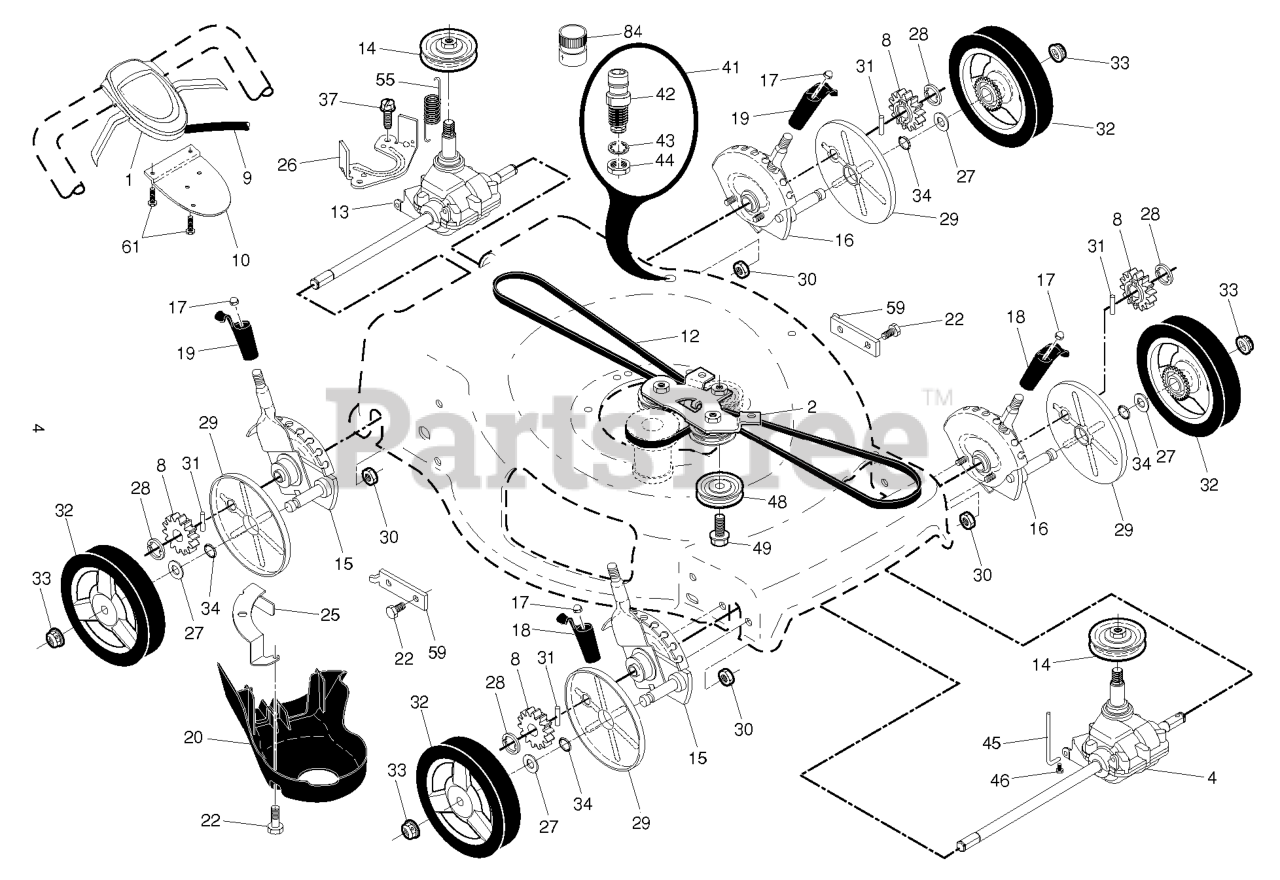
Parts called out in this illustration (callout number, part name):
1	CONTROL.22+AWD.AW2.BS.GRY/BLK
2	BRACKET.ASM.AWD.BZP
4	RP TRANSMISSION.22+.AWD.FRONT
8	PINIION.14.TOOTH.RGD
9	CABLE.DRIVE.RWD.WALK.
10	BRACKET.DRIVE.CONTR.GEN2.BLACK
12	BELT.DRIVE.AWD.PLUS.13
13	TRANSMISSION.22+AWD.WALK.MOWER
15	KIT.ADJ.22+QP.RT F/R.BLK.
16	KIT.ADJ.AWD.22+LT.F/R.BLK
17	NUT.PUSH.156
18	KNOB.ADJUSTER.LW.BLK
19	KNOB.ADJUSTER.REAR.BLACK
20	COVER.REAR.DRIVE.22+2013
22	BOLT.5/16HEX.WHS.HD
25	BRACKET.DRIVE.COVER.RGD.BZP
26	BRACKET.TRAN.BELTKEEPER.22+RGD
27	WASHER FLUT
28	E-RING 7/16 RE
29	COVER.DUST.WHEEL.INNER.WALK
30	NUT.FLANGE.1-4-20-SERR
31	PAWL, DRIVE
32	WHEEL.8".AWD.3SP.EXT.DR.GREY
33	NUT.HEX.FLANGE.3/8-16.LO(3 2)
34	O-RING..070X.487.NEOPRENE
41	KIT.WASH-OUT.PORT.ZINC.WALK
42	WASHOUT.PORT.ZINC.RGD.22+
43	WASHER.LOCK.INTERNAL.TOOTH
44	LOCKNUT.HEX.WITH.O-RING
45	BRACKET.AWD.FRONT.BELT.KEEPER
46	SCREW.HI-LO.5/16 X.75
48	RP PULLEY.IDLER.ASM
55	SPRING.RETURN.AUTO.
59	BRACKET.SUPPORT.22+RWGD.BZP
61	SCREW, PHILLIPS HEAD 10 X 5/8
84	COUPLING.QUICK CONNECT
